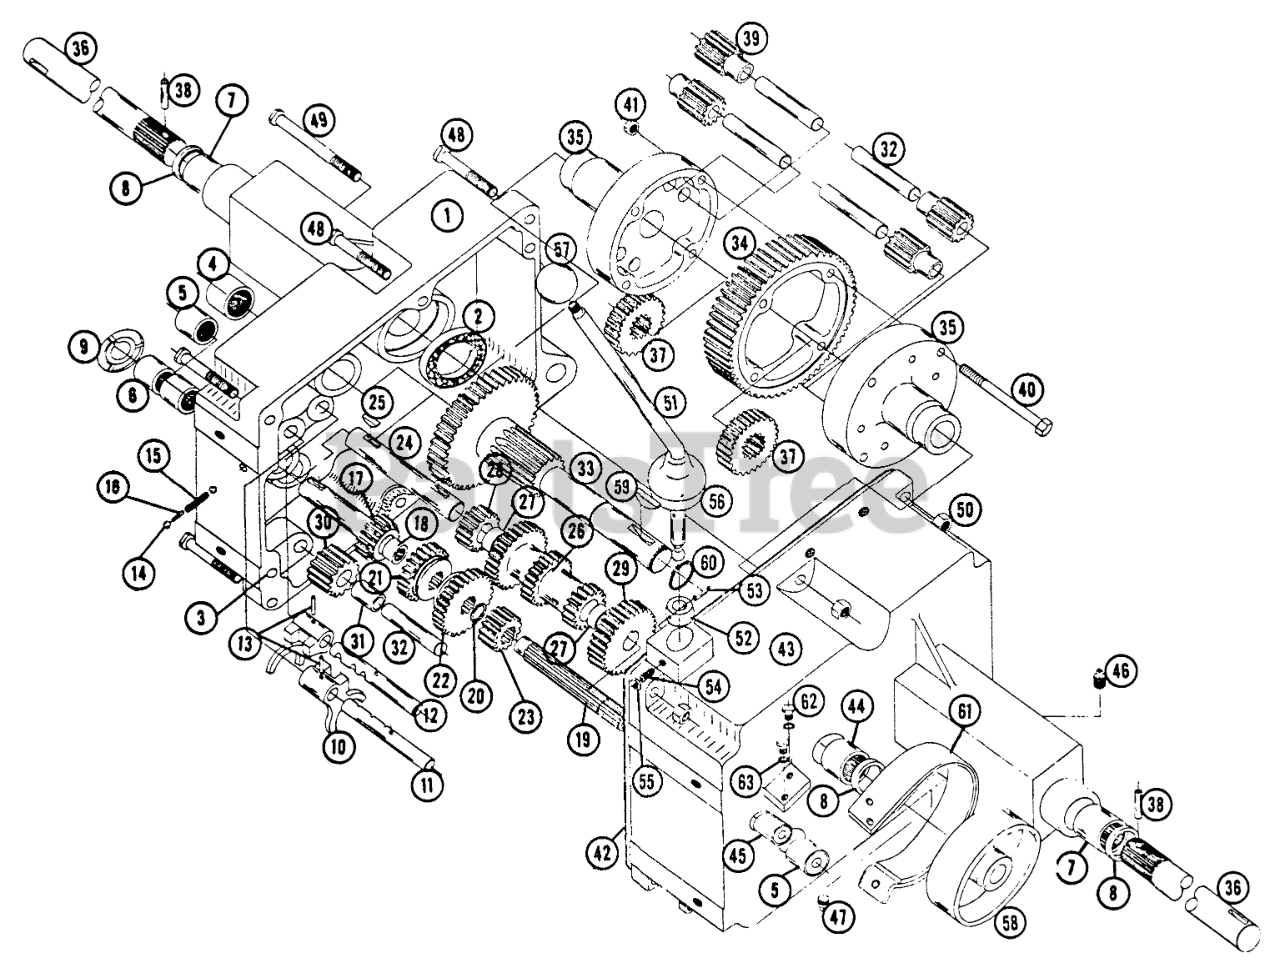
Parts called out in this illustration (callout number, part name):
3	PIN-DOWEL
4	BEARING-NEEDLE
5	BEARING-NEEDLE
7	BEARING-NEEDLE
10	FORK-SHIFT
13	PIN-ROLL
14	BALL-DETENT
18	BEARING-NEEDLE
20	Snap Ring 3/4 I.D.
23	GEAR
25	Key
27	BUSHING-BRONZE
29	GEAR-CLUSTER SHAFT
30	GEAR/BUSHING ASM-REVERSE IDLER
31	BUSHING
32	PIN-DIFFERENTIAL
34	SVC BULLT 394
35	DIFFERENTIAL CASE
37	AXLE GEAR
42	GASKET-TRANSMISSION
46	Plug 1/4 Pipe
47	Plug 3/8 Pipe
48	Bolt, 3/8 16 x 2
49	Bolt Hex 3/8-16 x 1
53	Roll Pin
54	Screw Soc. Hd.-Set 1/4-20 x 3/4
55	Nut 1/4-20
56	COVER-DUST
59	KEY-WOODRUFF
60	Snap Ring 1" Shaft
62	Bolt-1/4-20 x 5/8
63	Lockwasher
